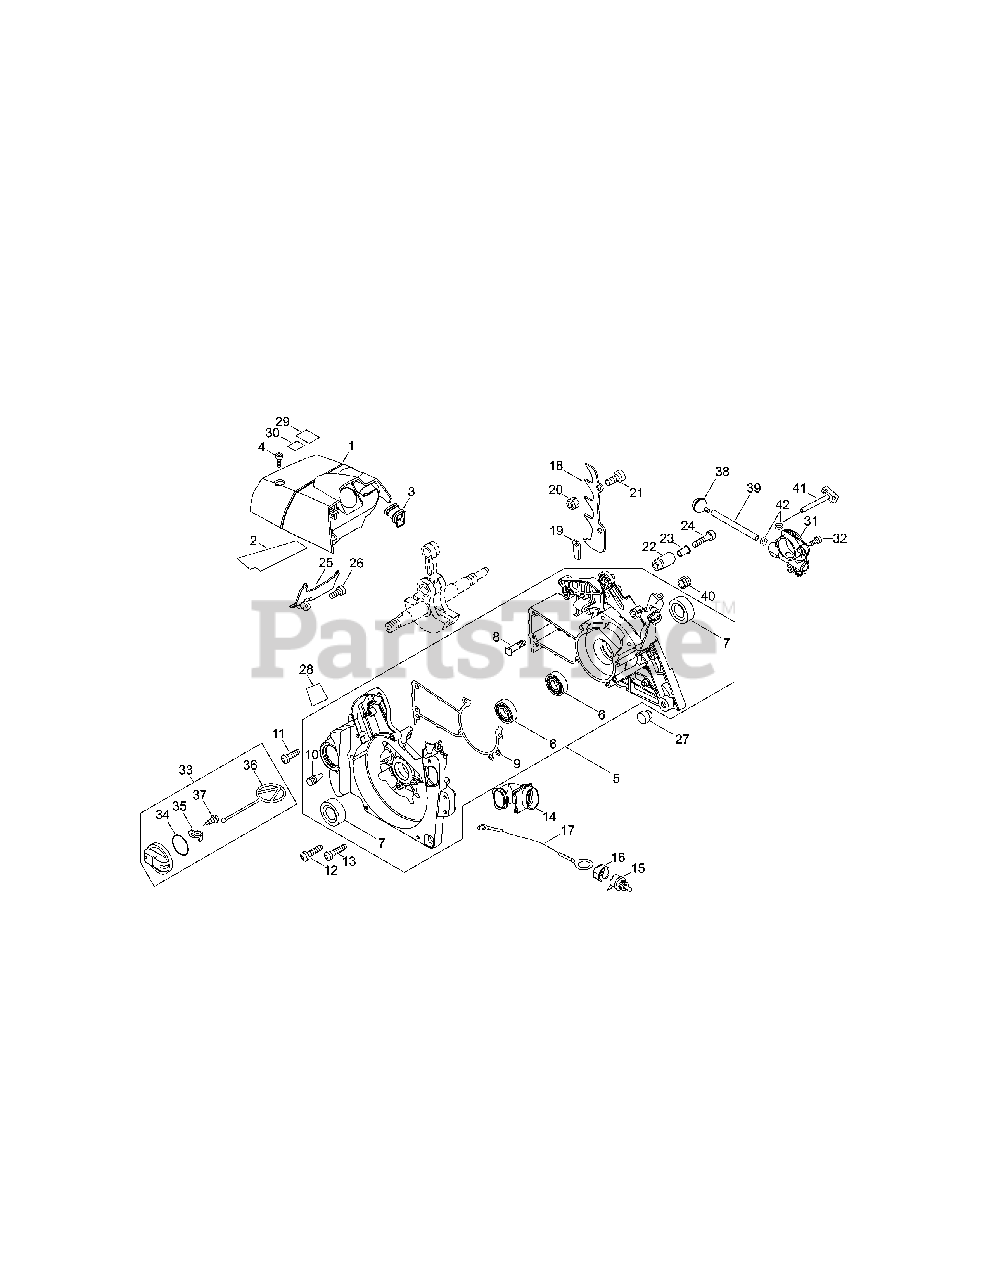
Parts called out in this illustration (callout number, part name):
1	COVER, ENGINE
2	SHIELD, HEAT 75×32×0.15
3	PIPE, INTAKE
4	BOLT, TORX 5×16
5	CRANKCASE KIT
6	BEARING, BALL 6202
7	SEAL, OIL 15
8	BOLT, STUD M8×1.25×34.5
9	GASKET, CRANKCASE
10	VENT ASSY
11	BOLT, TORX 5×20
12	BOLT, TORX 5×35
13	BOLT, TORX 5×25
14	PIPE, AIR INTAKE
15	SWITCH, ON-OFF
16	CAP, SWITCH
17	LEAD - GROUND L= 170
18	SPIKE, BUMPER
20	NUT, LOCK M5
21	BOLT, TORX 5×16
22	CHAIN CATCHER
23	COLLAR 5
24	BOLT, TORX 5×35
25	GUIDE, AIR
26	BOLT, TORX 5×16
27	CUSHION
28	CUSHION
29	LABEL, CAUTION
30	LABEL, CAUTION
31	AUTO-OILER ASSY
32	BOLT, TORX 4×12
33	CAP ASSY, OIL
34	O-RING 28
35	RETAINER, CONNECTOR
36	CONNECTOR, CAP L= 60 MM
37	SCREW, TAPPING 3×8
38	FILTER, OIL
39	PIPE, FUEL 3×6×210 BLACK
40	GROMMET
41	PIPE, OIL
42	CLIP Ø6
